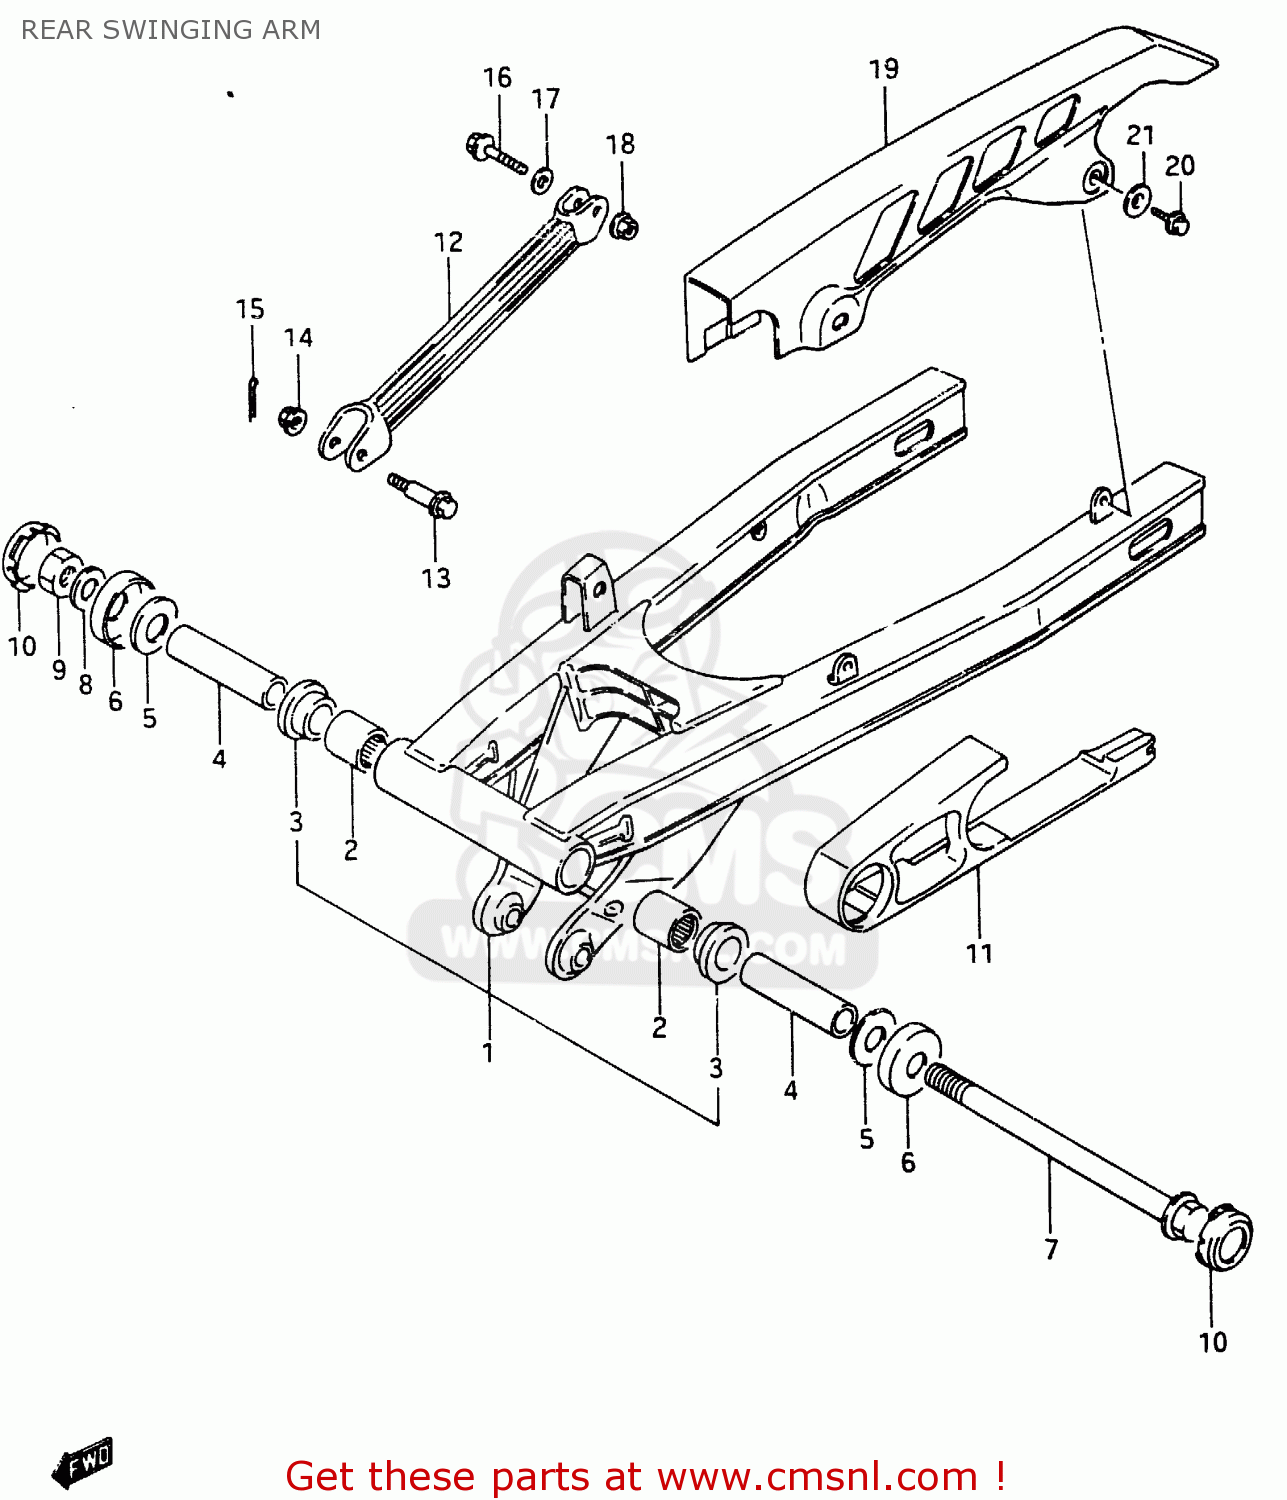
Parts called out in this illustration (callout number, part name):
1	SWINGING ARM ASSY, REAR
2	BEARING(20X27X30)
3	BUSHING
4	SPACER, PIVOT
5	WASHER
6	CVR,RR SWGARM DUST SEAL(OD:40)
7	SHAFT, PIVOT
8	WASHER
9	NUT
10	CAP,SWINGINGARM PIVOT
11	BUFFER, CHAIN TACH DIFENCE
12	TORQUE LINK, REAR
13	BOLT
14	NUT
15	PIN 20X20
16	BOLT(10X38)
17	WASHER
18	NUT
19	CASE, CHAIN
20	BOLT
21	WASHER
